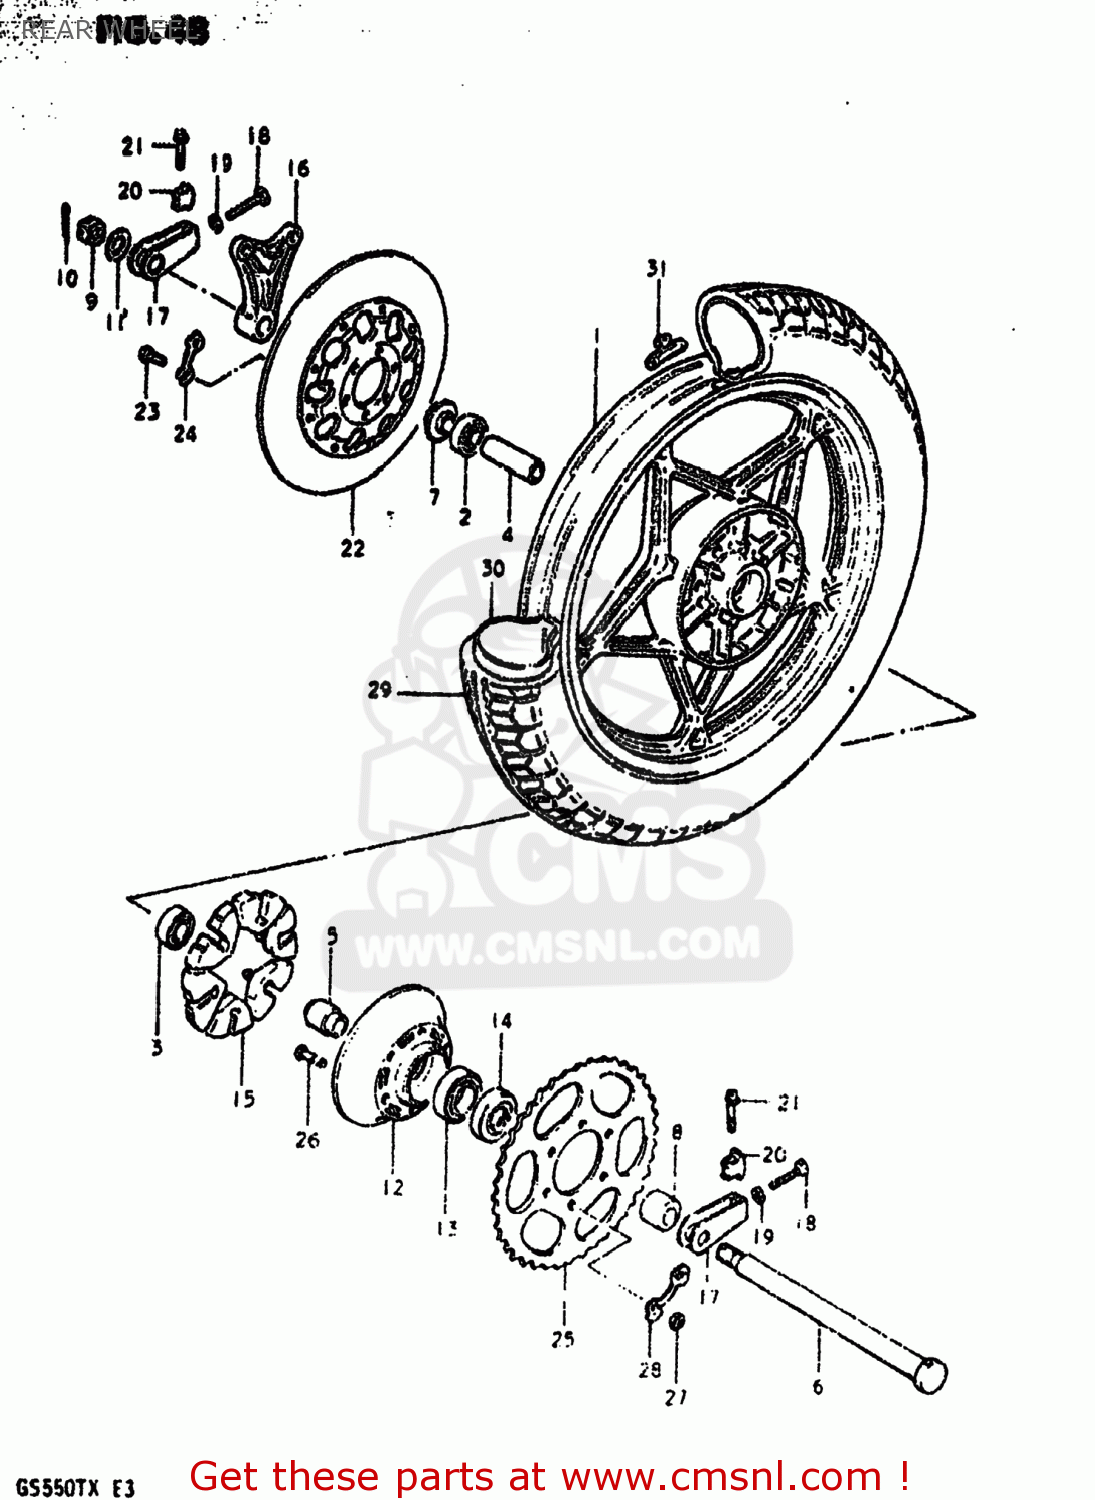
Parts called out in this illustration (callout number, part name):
1	WHEEL,REAR
2	BEARING
3	BEARING
4	SPACER(20.5X28X88)
5	RETAINER,REAR SPROCKET D
6	AXLE,REAR
7	SPACER,REAR AXLE
8	SPACER (17X33X21.1)
9	NUT
10	PIN,COTTER
11	WASHER (17X30X3.2)
12	DRUM,REAR SPROCKET MOUNT
13	BEARING
14	SEAL,OIL(33X62X7)
15	ABSORBER,REAR HUB SHOCK
16	BRACKET,RR,CALIPER
17	ADJUSTER,CHAIN
18	BOLT
19	NUT
20	SUPPORTER,CHAIN ADJUST
21	BOLT
22	DISC,BRAKE
23	BOLT(8X30)
24	WASHER
25	SPROCKET,RR
26	BOLT
27	NUT
28	WASHER
29	TIRE
30	TUBE ASSEMBLY,WHEEL,INNER
31	BALANCER,WHEEL
